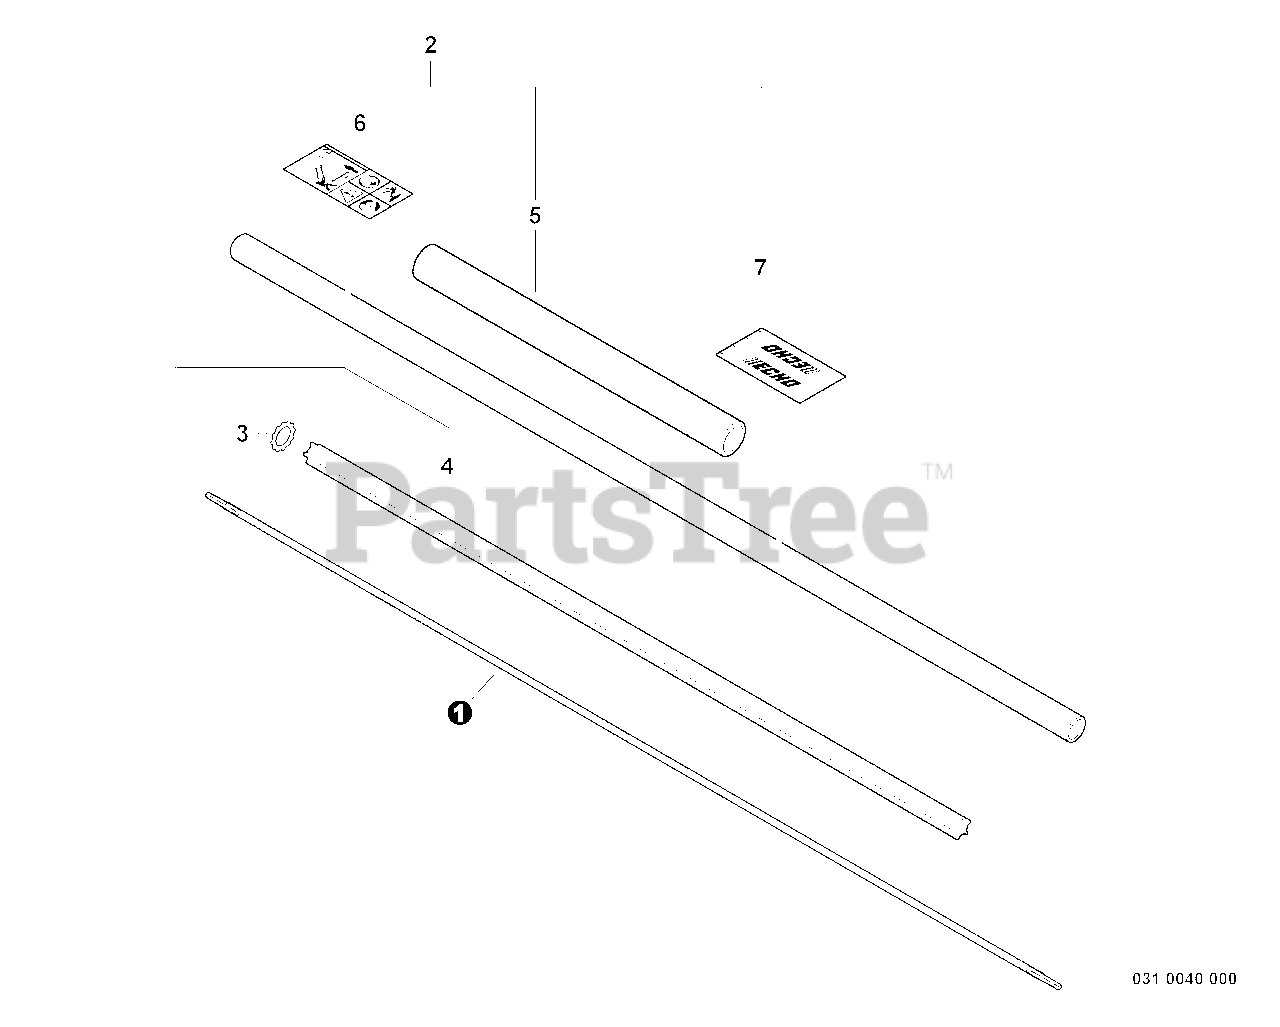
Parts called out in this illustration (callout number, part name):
1	DRIVESHAFT - FLEXIBLE
2	MAIN PIPE ASSY
4	LINER - FLEXIBLE
5	GRIP, FRONT
6	LABEL, CAUTION
7	LABEL, HANDLE LOCATION
